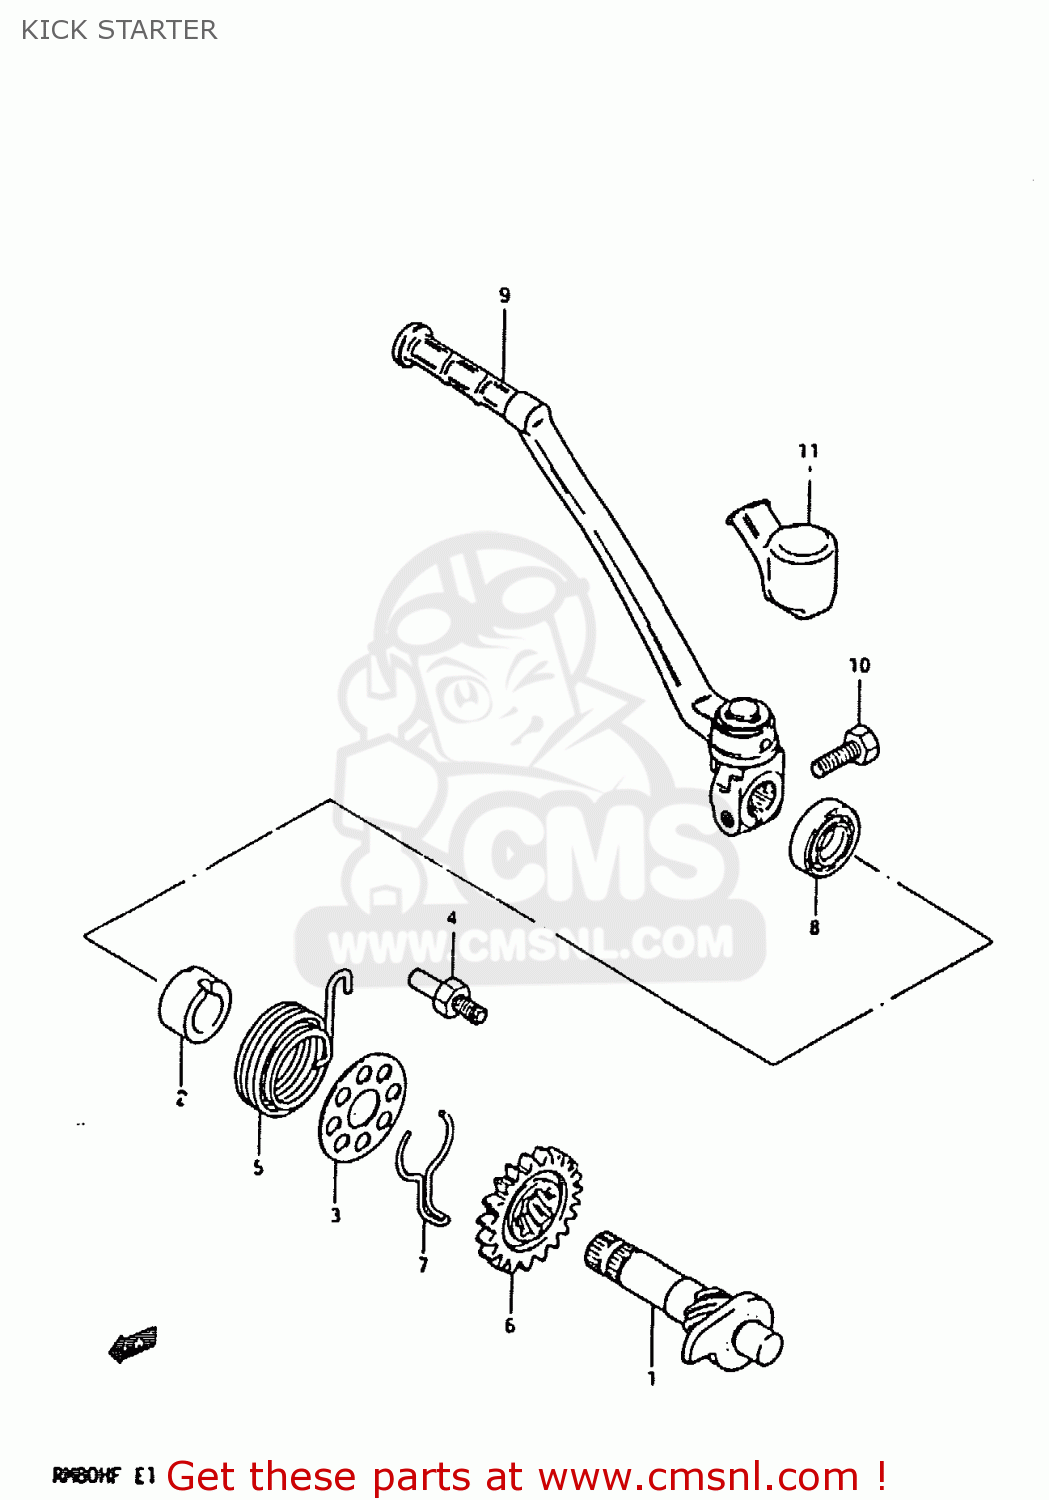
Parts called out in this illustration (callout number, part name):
1	SHAFT,KICK STARTER
2	GUIDE,KICK STARTER SFT SPRING
3	HOLDER,KICK STARTER SHAFT SPR
4	BOLT,KICK START SHAFT SPR HOOK
5	SPRING
6	GEAR,KICK STARTER DRIVE
7	SPRING,RETAINER
8	SEAL,OIL(14X24X6)
9	LEVER ASSEMBLY,KICK STARTER
10	BOLT
11	COVER,KICK LEVER JOINT
